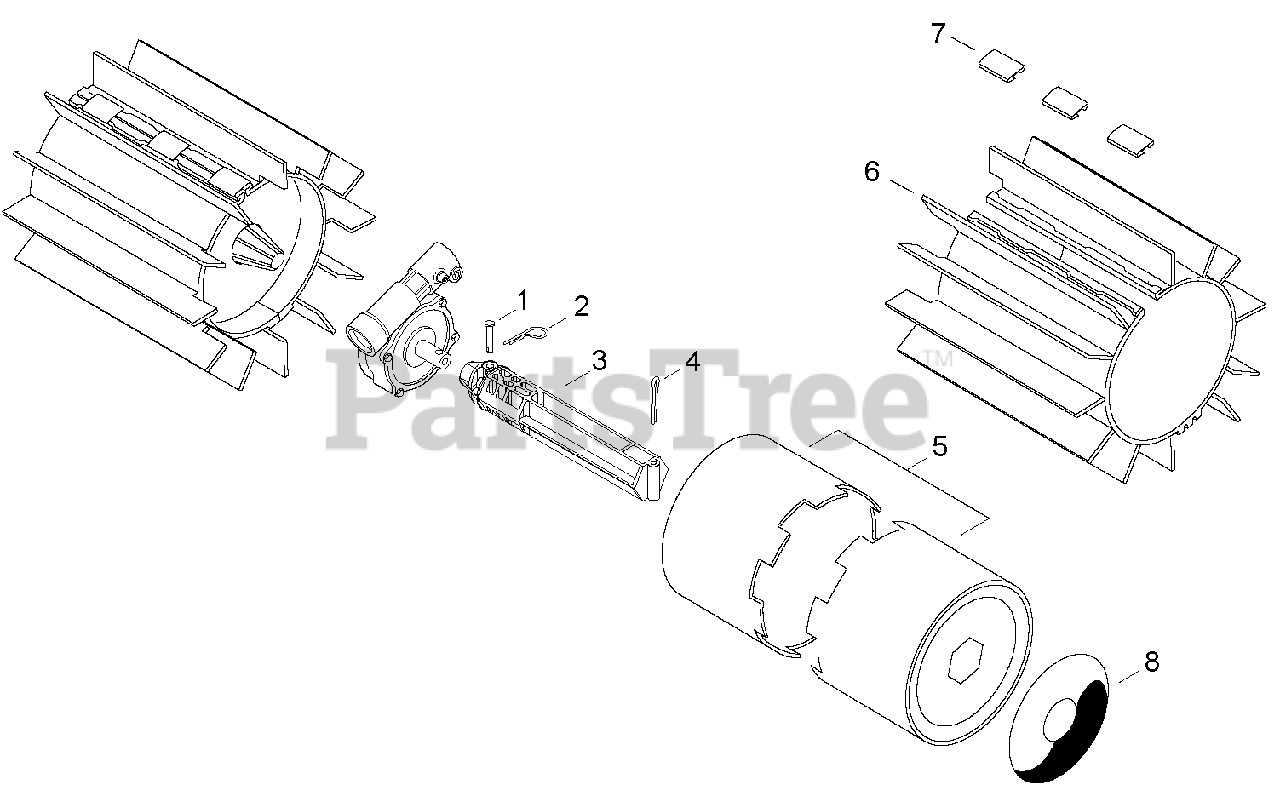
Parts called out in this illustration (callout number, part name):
1	PIN - CLEVIS
2	PIN - HITCH
3	AXLE, DRUM
4	PIN, SPLIT
6	BELT, SWEEPER
7	CLIP, BELT
8	LABEL - POWERBROOM
